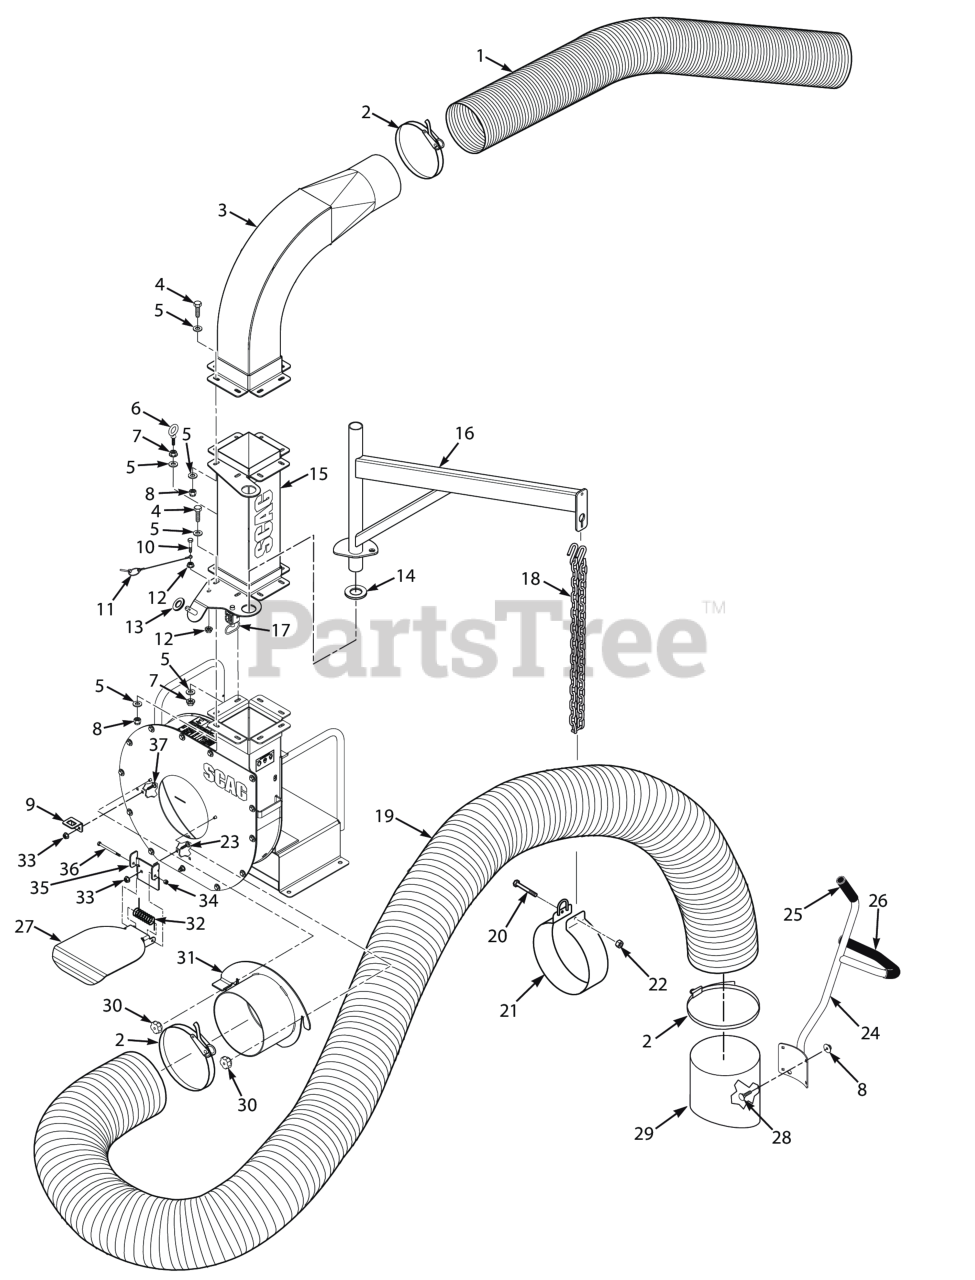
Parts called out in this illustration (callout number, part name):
1	Hose, Clear Poly 7" x 30"
2	Strap, Ratchet- 66 x 1"
3	Discharge Elbow Weldment
4	Bolt, Hex Head 3/8-16 x 1-1/4", Kawasaki FX / FS
5	Flatwasher, 3/8" Special (.391 x .938 x .105)
6	Eyebolt, 3/8"
7	Nut, Serrated Flange 5/16-18 (Right Front Engine Mounting, Briggs and Kohler Only)
8	HEX NUT, ELASTIC STOP LOCK, 3/8-16
9	Bracket, Brake Switch
10	SERR. FLG. HEX HEAD CAPSCREW, 5/16-18 X 3/4
11	Quick Pin Assembly w/Lanyard
12	NUT, 1/4-20 SERRATED FLANGE HEX HEAD
13	Washer, Rubber
14	Disk, Anti-Friction
15	Stack w/Decal, Discharge
16	Boom Weldment
17	Spring
18	Chain w/2-Hooks
19	Hose, 10" x 12' - .045 w/wearstrip
20	Bolt, Hex Head 5/16-18 x 3-1/2"
21	Band Assembly, Hose Support - 10"
22	HEX NUT, ELASTIC STOP LOCK, 5/16-18
23	Bolt, Carriage 5/16-18 x 3/4"
24	Handle w/Grips
25	Grip, Handle 1-1/4" x 6"
26	Grip, Handle 1-1/4" x 20"
27	Safety Switch Door
28	Carriage Bolt, 3/8-16 x 1.0"
29	Adapter w/Decal
30	Knob, 3/8-16 Locking
31	Hose Mount Weldment
32	Spring, Discharge Chute
33	Nut, Serrated Flange 5/16-18 (Right Front Engine Mounting, Briggs and Kohler Only)
34	HEX NUT, ELASTIC STOP LOCK, 5/16-18
35	Mounting Bracket, Safety Switch Door
36	Bolt, 5/16-18 x 4-3/4" Hex Head
37	Bolt, Carriage 5/16-18 x 3/4"
